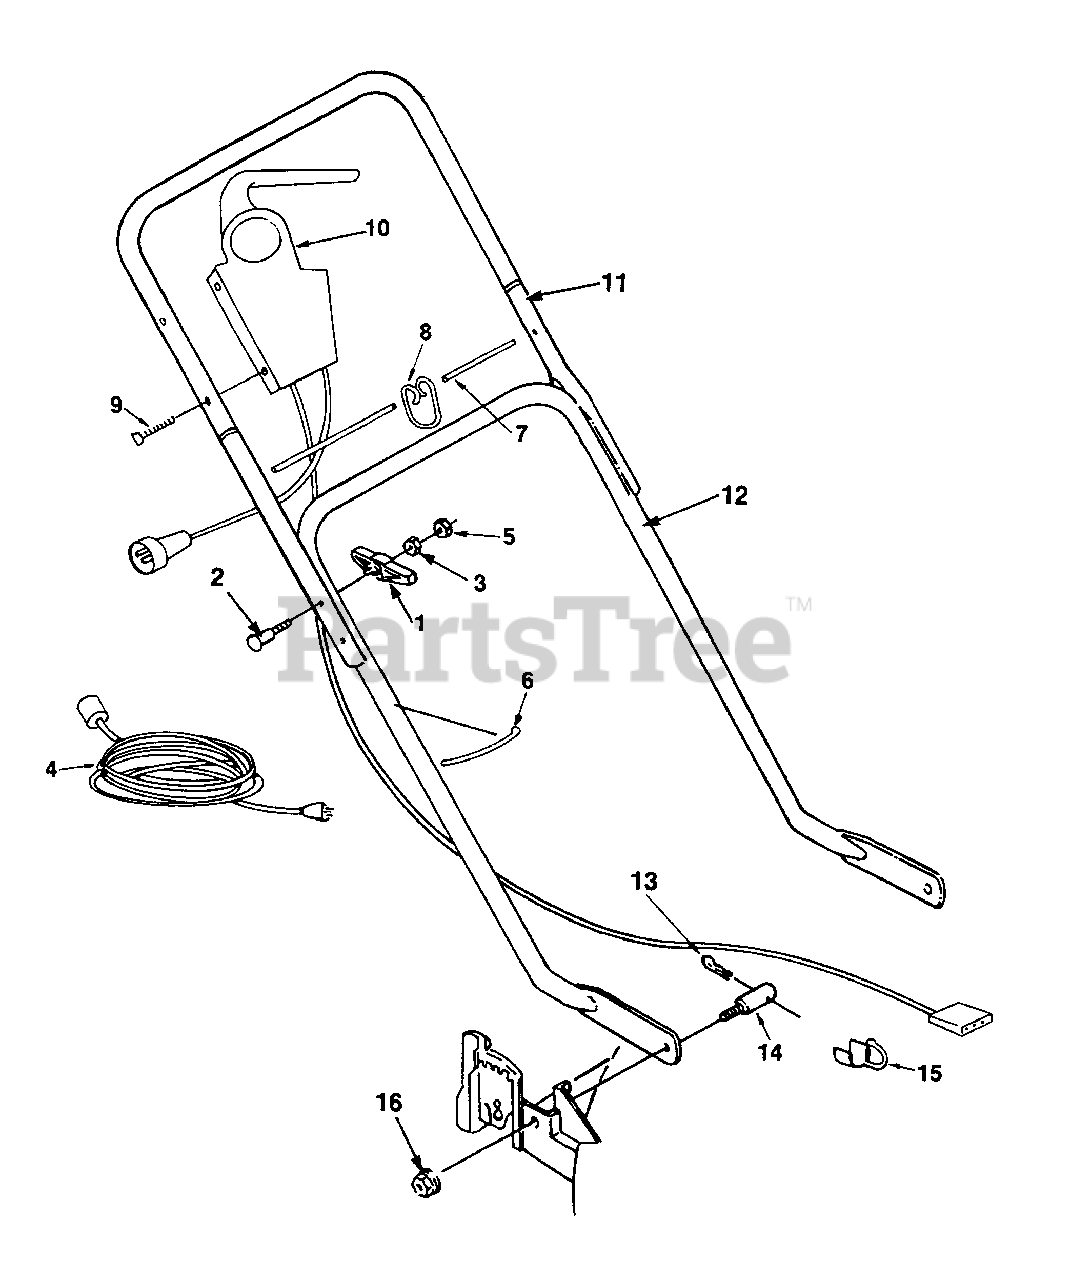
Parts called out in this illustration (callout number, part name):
1	KNOB- Handle
3	NUT- Hex
4	CORD- Extension (access.)
5	NUT- Hex lock
6	TIE- Cable
7	ROD- Cord hanger
8	LINK- Lift
9	SCREW- Flat hd
10	CONTROL
11	HANDLE- Upper
12	HANDLE- Lower
13	PIN- Hair
15	BUSHING- Strain relief
16	NUT- Flanged
